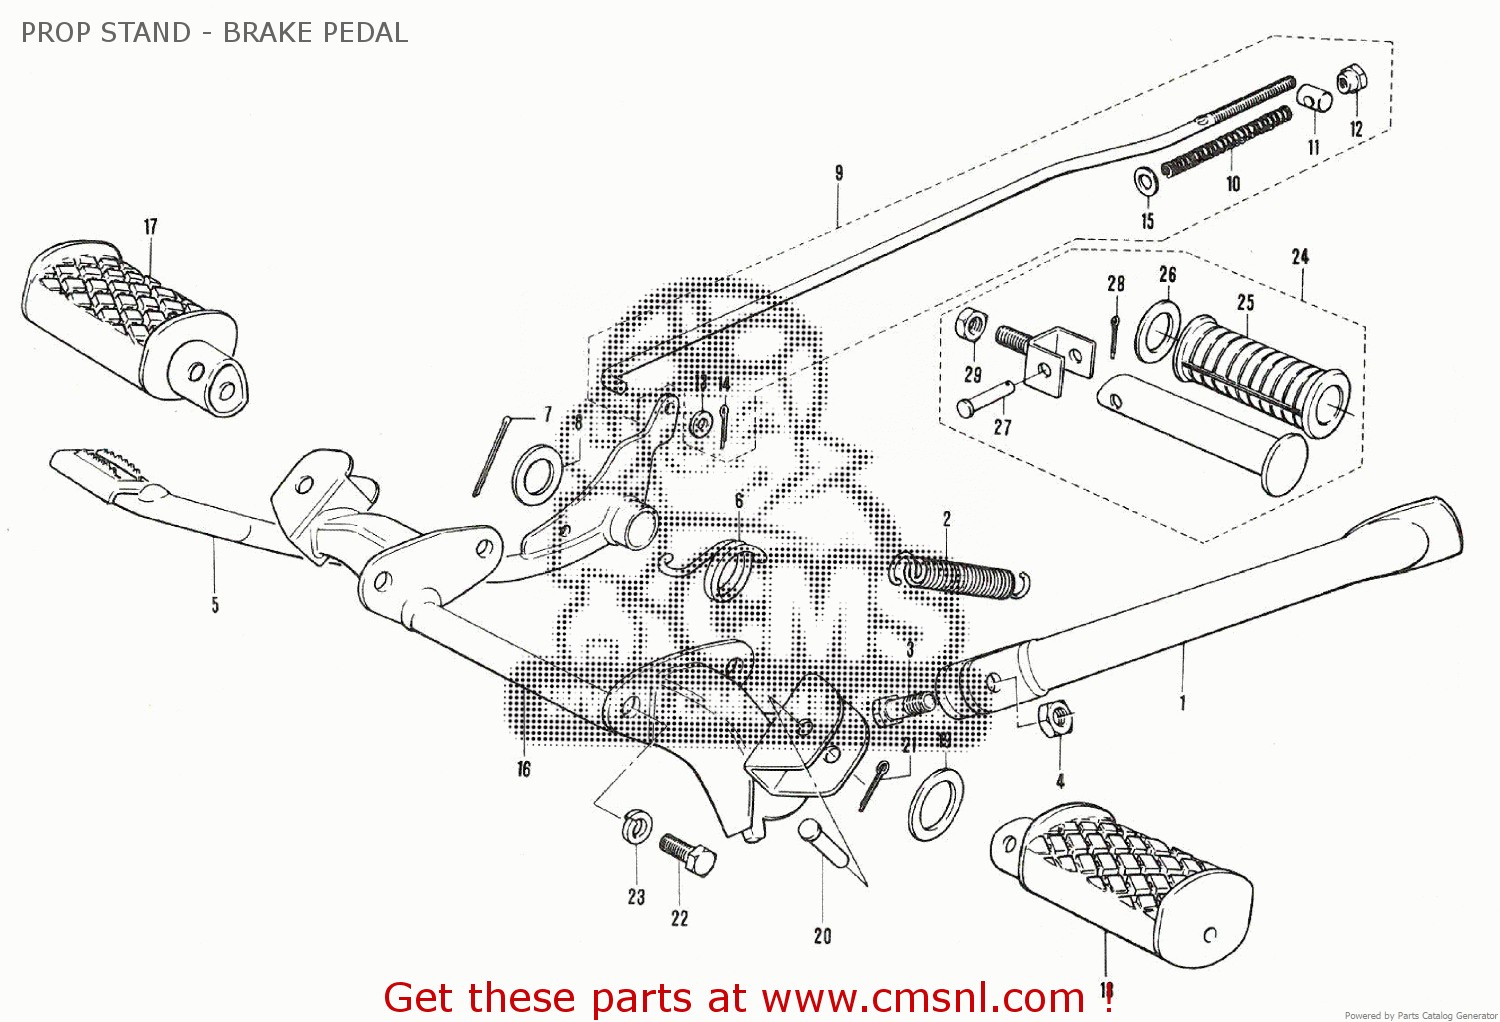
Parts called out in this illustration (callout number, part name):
1	STAND,SIDE
2	SPRING
3	BOLT
4	NUT
5	PEDAL,BRAKE
6	SPRING
7	PIN
8	WASHER(15.5X26X2.3)
9	ROD ASSY,RR BRAKE
10	SPRING
11	PIN(11X18)
12	NUT
13	WASHER
14	PIN
15	WASHER
16	BAR,FRONT FOOTREST
17	RUBBER,FOOTREST,RIGHT
18	RUBBER,FOOTREST,LEFT
19	WASHER
20	PIN
21	PIN
22	BOLT
23	LOCK WASHER
24	FOOTREST ASSEMBLY,REAR
25	RUBBER,PILLION FOOTREST
26	WASHER (19.5X32X2)
27	PIN
28	PIN
29	NUT
